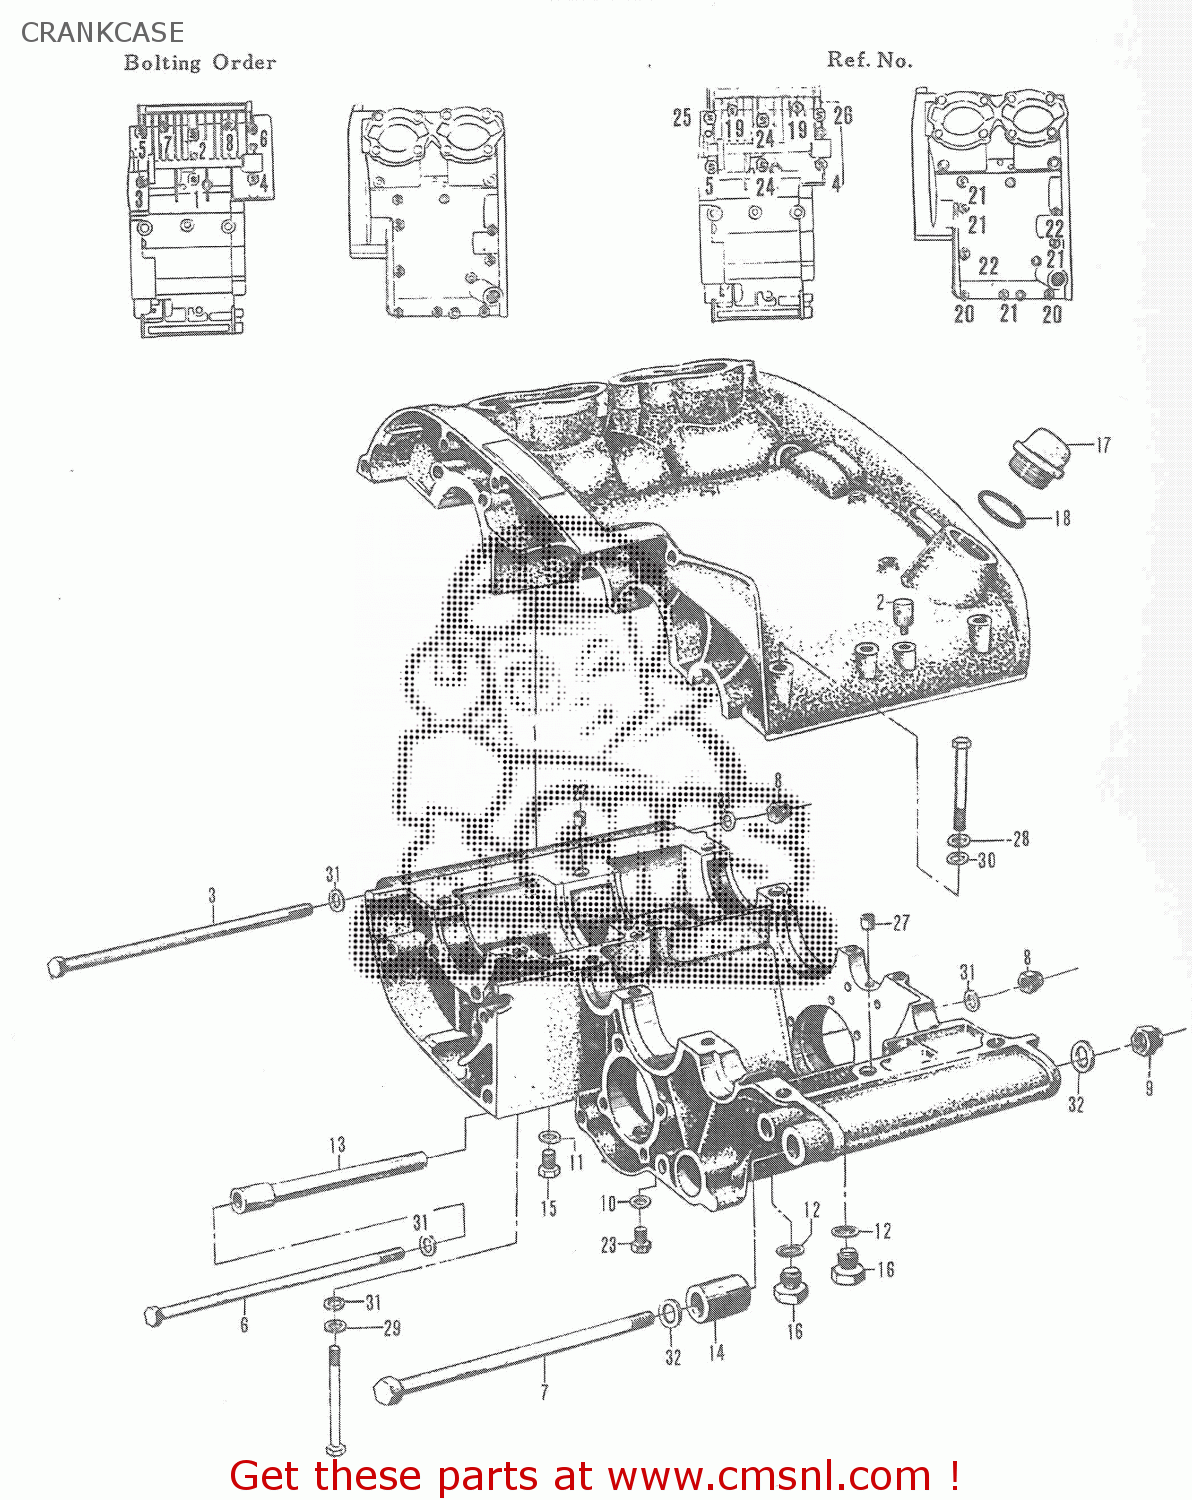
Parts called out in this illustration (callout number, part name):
1	CRANKCASE ASS'Y
2	PLUG,TRANSMISSION BREATHER
3	ENGINE FRONT MOUNTING BOLT
4	BOLT 8X100
5	BOLT 8X110
6	BOLT
7	BOLT 10X215
8	NUT
9	NUT
10	GASKET
11	GASKET(10X14X3.6) (NAS)
12	GASKET(14X19.2X2) (NAS)
14	SPACER
15	PLUG
16	PLUG(MAGNETO)
17	OIL FILLER PLUG
18	O RING(D:2.4,ID:21.8)
19	STRONG HEXAGON BOLT
20	STRONG HEXAGON BOLT
21	STRONG HEXAGON BOLT
22	STRONG HEXAGON BOLT
23	SMALL HEAD HEXAGON BOLT
24	STRONG SMALL HEAD HEXAGON BOLT
25	STRONG SMALL HEAD HEXAGON BOLT
26	STRONG SMALL HEAD HEXAGON BOLT
27	DOWEL PIN
28	LOCK WASHER
29	LOCK WASHER
30	SMALL FLAT WASHER
31	SMALL FLAT WASHER
32	SMALL FLAT WASHER
